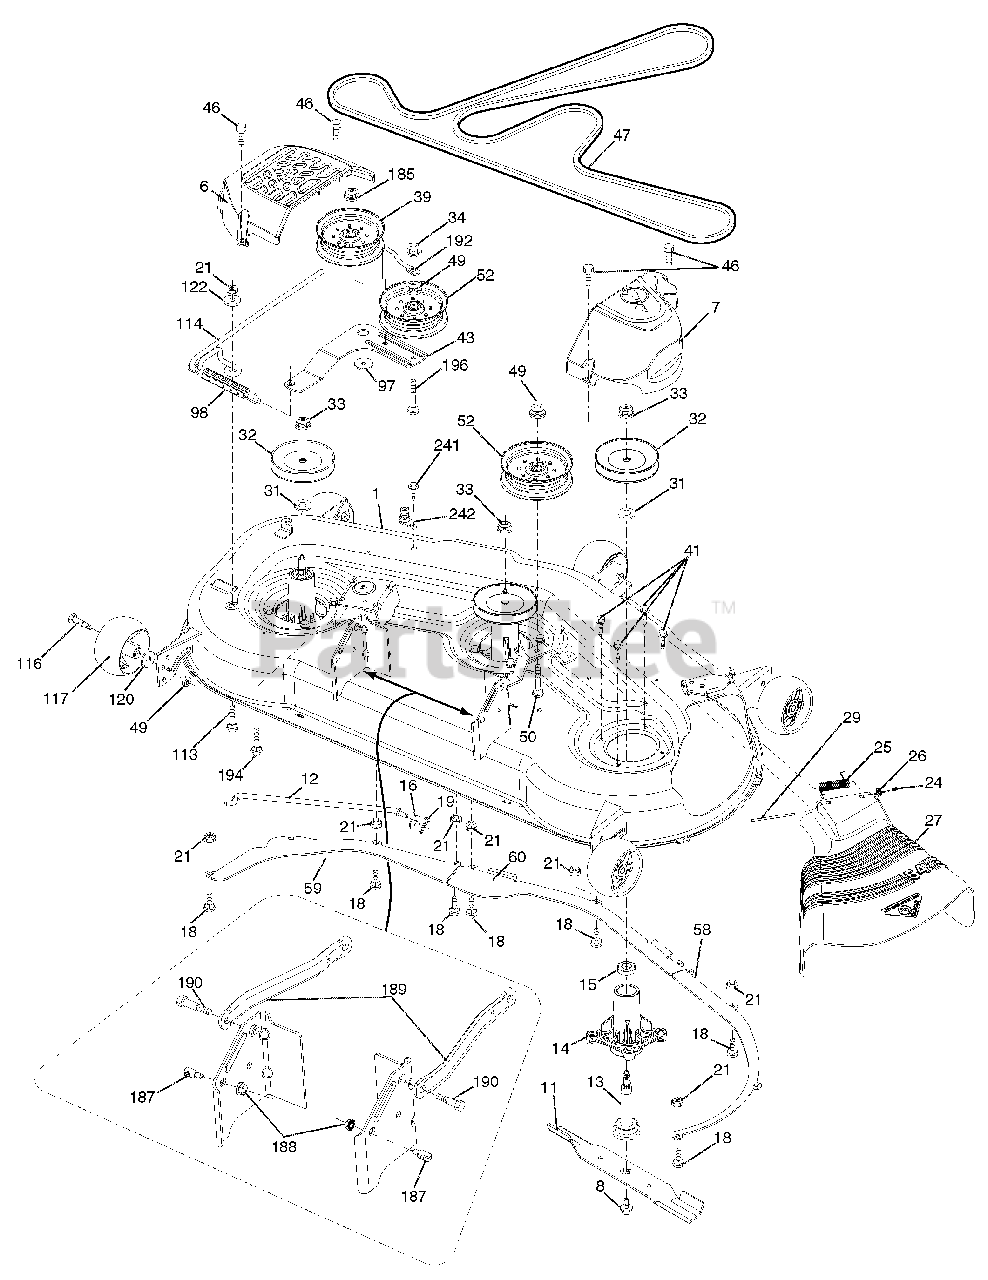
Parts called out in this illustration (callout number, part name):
1	DECK.WELDMENT.54"
6	COVER.MANDREL.LH.54"2006
7	COVER.MANDREL.RH.54"2006
8	BOLT/WASHER ASM.7/16-20.UNF
11	BLADE.BAGGING.54"
12	ROD.ANTI SWAY.48/54"K46.TEX
13	SHAFT ASM.MANDREL.48/54"SVC
14	HOUSING.MANDREL.4PT.SERVICE
15	BEARING.BALL.MANDREL
16	Washer 13/32 x 13/16 x 12 Ga.
18	BOLT.RDHD.SQNK.5/16-18 X 5/8
19	PIN.COTTER.5/16.BOW TIE LOCK
21	Nut, Hex, Crownlock 5/16-18
24	CAP.SLEEVE..80X.112.BLK.MOWER
25	SPRING.TORSION.48"
26	NUT.PUSH.PHOS.& OIL
27	DEFLECTOR SHIELD
29	ROD.HINGE.42/46"
31	WASHER.SPACER.MANDREL
32	MANDREL.PULLEYS.42,44,50
33	NUT.FLANGE.LOCK.TOP
34	Nut, Hex, Crownlock 3/8-16
39	PULLEY.IDLER.4.50.HUB.SPECIAL
41	HEX HEAD BOLT
43	ARM.ILDER
46	SCREW.THD.ROLL.1/4-20 X 5/8
47	BELT.DRIVE.54"2006
49	Nut, Hex, Flangelock 3/8-16
50	BOLT.RD.HD.SQ.NK.3/8-16UNC X 2
52	PULLEY.IDLER.4.50.RAW
58	BAFFLE.RIGHT.54"
59	BAFFLE.LEFT.54"
60	BAFFLE.CENTER.54"MOWER
97	WASHER.FLAT.HARDENED
98	SPRING.DRIVE.DECK.2006
113	BOLT.CARR.5/16-18UNC X 1
114	ROD.TENSION.RELIEF
116	BOLT.SHOULDER.3/8-16X3-5/8.GR5
117	WHEEL.GAUGE.RALLY.
120	WASHER.13/32 X 1-1/4 X 12 GA.
122	BUSHING.RELIEF.TENSION
185	NUT.LOCK.FLANGE.7/16-14.GR5
187	STUD.FASTNER.W/'D'ANTI-ROTATIO
188	Nut, Lock Hex Flange 5/16-18 u
189	ARM.SUSPENSION.MOWER.REAR
190	BOLT.SHOULDER
192	KEEPER.BELT.IDLER.54"TL
194	BOLT CARR SQNK 3/8-16 X 2-1/4
196	BOLT.RDHD.SQNK.3/8-16X2-1/2.G5
242	PORT WASHOUT
